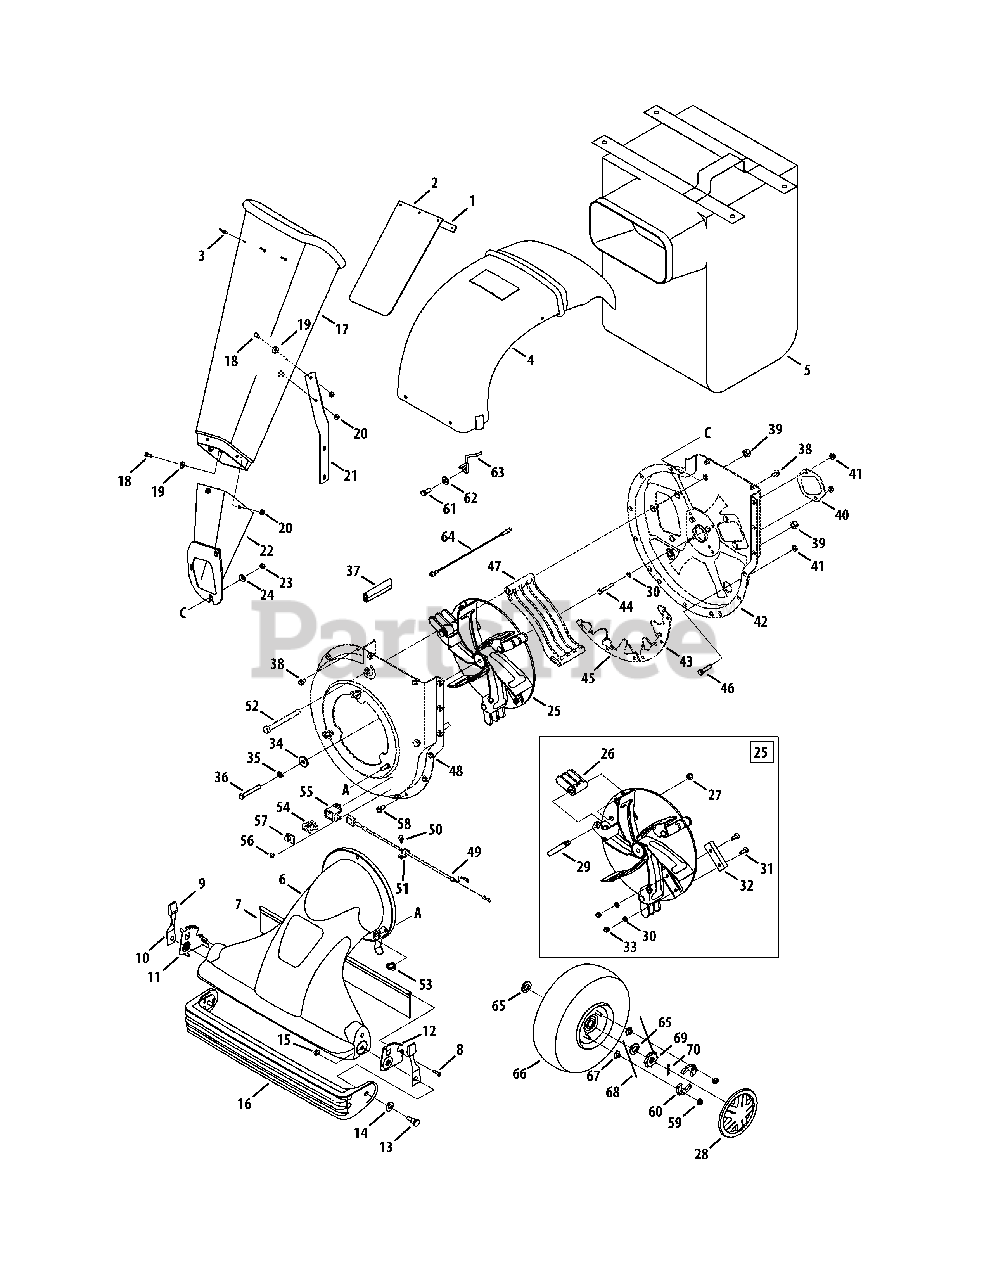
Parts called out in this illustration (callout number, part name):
1	Chute Flap Strip
2	Chute Flap
3	Pop Rivet
4	Discharge Chute
6	Nozzle Assembly
7	Nozzle Flap
9	Height Adjustment Knob
10	Spring Lever
11	Index Bracket RH
12	Index Bracket LH
13	Shoulder Screw
14	Flat Washer, .510 x 1.12 x.060
15	Hex Flange Lock Nut, 3/8-16
16	Door Assembly
17	Chipper Chute
18	Hex Cap Screw, 1/4-20 x.620
19	Flat Washer, .28 ID x.74 OD
20	Hex Lock Nut, 1/4-20
21	Support Bracket
22	Chipper Chute Assembly
23	Hex Nut, 5/16-18
24	Bell Washer, .340ID x.872OD
25	Impeller Assembly Complete
26	Flail Blade
27	Jam Lock Nut, 3/8-16
29	Shoulder Pin, .5 x 2.625
30	Lock Washer, 5/16
31	Cap Screw 5/16-24 x 1.0
32	Chipper Blade
33	Hex Lock Nut 5/16-24
34	Flat Washer, .406 x 1/1/4
35	Lock Washer, 3/8
36	Hex Cap Screw, 3/8-24 x 2.75
37	Rubber Seal
38	Hex Washer Screw, 5/16-18
39	Hex Lock Nut, 1/2-13
40	Chipper Blade Cover
41	Hex Flange Lock Nut 5/16-18
42	Housing Assembly, Inner Flail
43	Upper Shredder Blade
44	Hex Cap Screw, 5/16-18 x 2
45	Flail Housing Blade
46	Hex Cap Screw, 5/16-18 x.75
47	Discharge Screen
48	Housing Assembly, Outer Flail
49	Wire Harness
50	TT Screw, 1/4-14 x 0.625"
52	Hex Cap Screw, 1/2-13 x 5.0
53	Knob, 5/16-18
55	Safety Switch Mounting Cover
56	Hex Washer Screw
57	Switch Cover
58	LD Screw, 5/16-18 x 0.75"
59	Hex Flanged Lock Nut, 1/4-20
60	Pawl, .345 ID - LH
60	Pawl, .345 ID - RH
61	Hex Cap Screw, 5/16-24 x.75
62	Flat Washer, .344 x.75 x.12
63	Belt Keeper
64	Adapter Harness Assembly
65	Flat Washer, 5/8 ID x 1.0 OD
66	Wheel Complete 10 x 4 x 4
67	Hex Nut, 1/4-20
68	Plastic Spring Ratchet
69	Wheel Ratchet 1.62 OD x.5 serr
70	Cotter Pin
